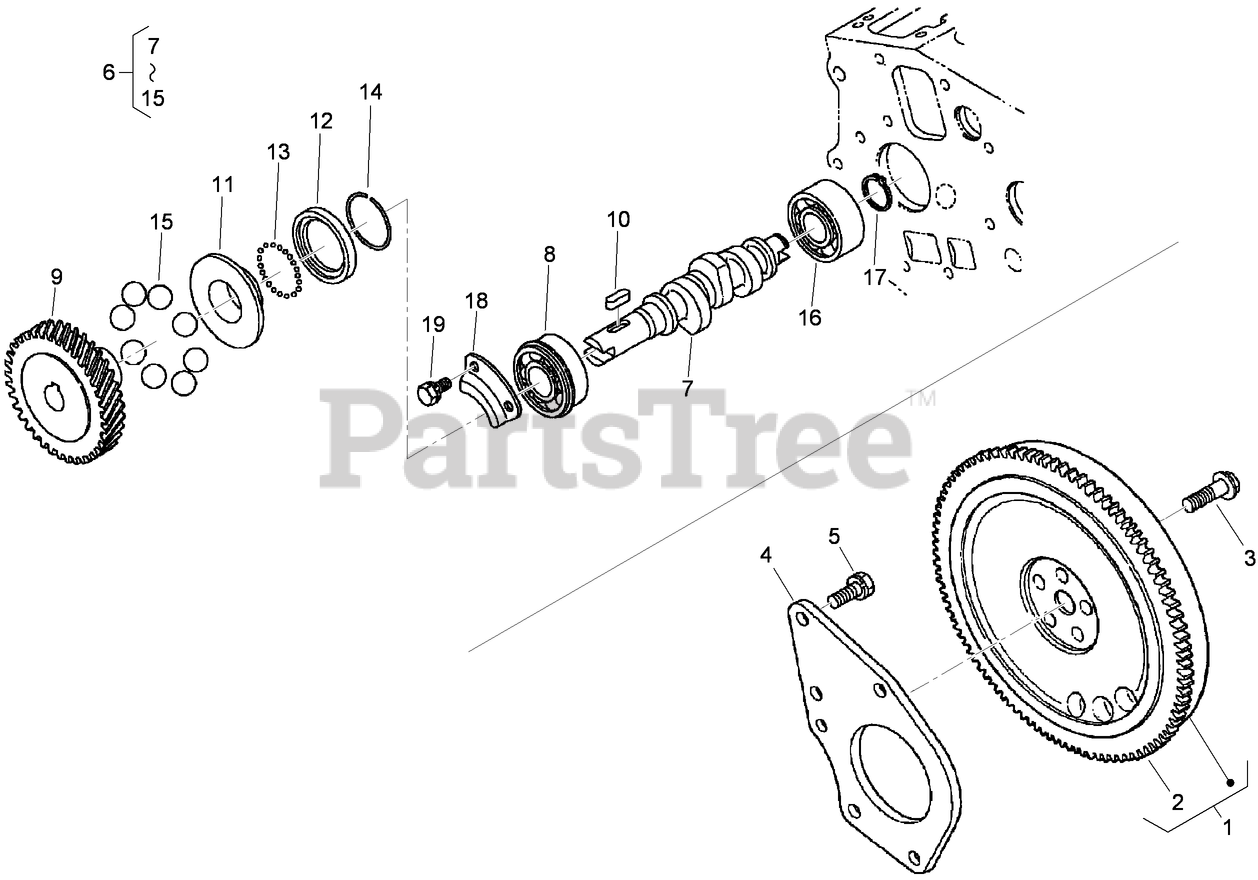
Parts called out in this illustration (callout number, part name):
1	FLYWHEEL
2	GEAR-RING
3	BOLT-FLYWHEEL
4	PLATE-END, REAR
6	FUEL CAMSHAFT ASM
7	CAMSHAFT-FUEL
8	BEARING-BALL
9	GEAR-PUMP, INJECTION
10	KEY-FEATHER
11	SLEEVE-GOVERNOR
12	CASE-BALL, GOVERNOR
14	CIRC-CLIP
16	BEARING-BALL
17	CIRC-CLIP, EXTERNAL
18	STOPPER-FUEL, CAMSHAFT
